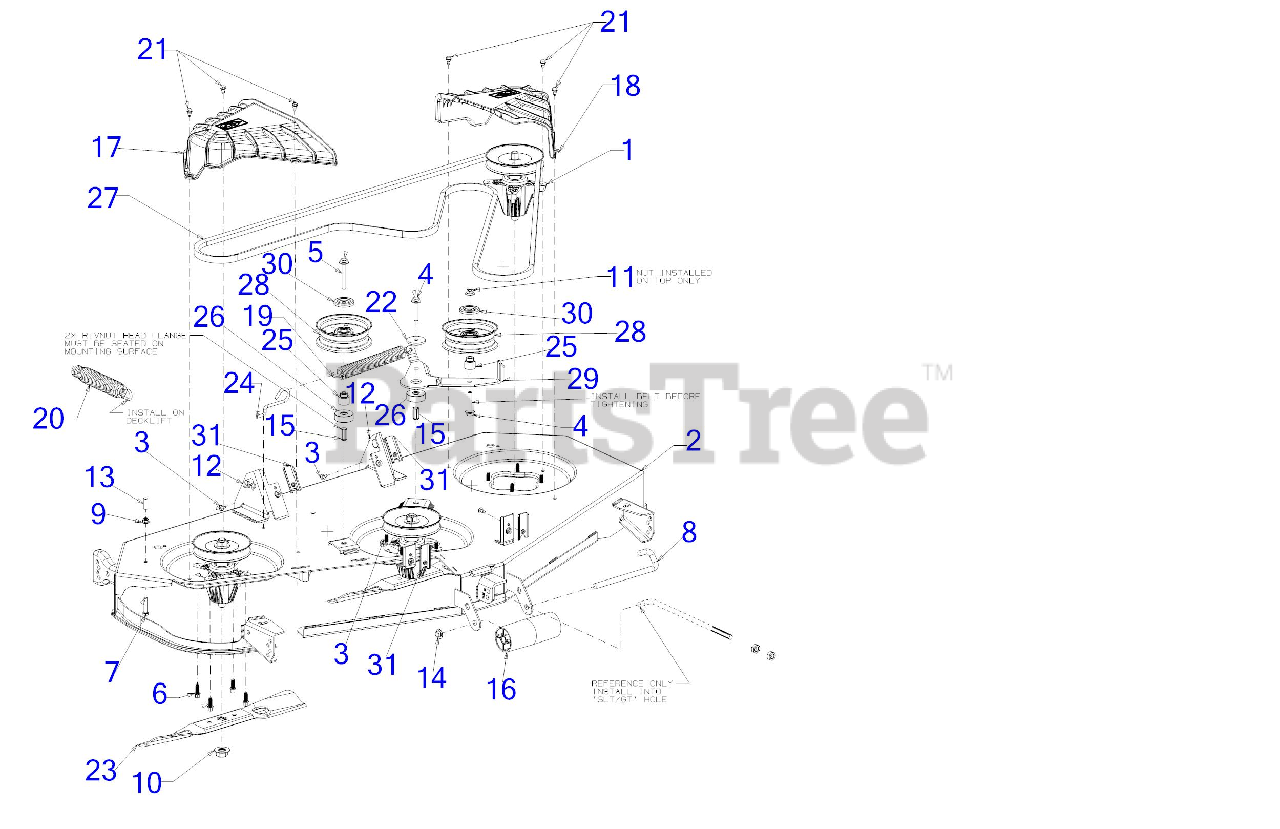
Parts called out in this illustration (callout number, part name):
1	SPINDLE ASSEMBLY
1	Cub Cadet 54" SPINDLE (06978 W/HDW)
2	54" DECK SHELL
3	SCREW M6-1 x .625
4	SCREW 3/8-16 x 2.0
5	SCREW 3/8-16 x 2.75 GR5
6	SCREW 5/16-18 X .875
7	SCREW 5/16-18 x 1.5 LG
8	ROLLER PIN 1/2 x 7.31
9	FLANGE LOCK NUT 5/16-18
11	FLANGE LOCK NUT
12	BOW TIE COTTER PIN
15	NUT RIVET 3/8-16
17	SPINDLE COVER (RH)
18	SPINDLE COVER (LH)
19	EXTENSION SPRING
20	LIFT ASSIST SPRING
21	SHOULDER SCREW 1/4-20 x .50
22	SHOULDER SPACER
23	18.61" BLADE (2N1)
23	Cub Cadet 54" HI LIFT BLADE SET
23	Genuine Factory Parts 54" BLADE SET
23	54" 6 PT STAR LOW LIFT/SAND BLADE
23	Cub Cadet 54" LOWLIFT BLADE SET
23	Genuine Factory Parts 54" LOWLIFT BLADE SET
23	54" 6 PT STAR XTREME MULCH BLADE
23	Cub Cadet 54" XTREME BLADE SET
23	Genuine Factory Parts 54" XTREME MULCH BLADE SET
24	DECK SPRING HOOK
25	SHOULDER SPACER
26	SPACER .385ID x 1.75OD x .585THK
27	V-BELT B SEC x 139 LG
27	Cub Cadet 54" DECK DRIVE BELT
27	Genuine Factory Parts 54" DECK BELT
28	IDLER PULLEY 4.50" DIA
29	IDLER PIVOT BRACKET
30	IDLER PULLEY CAP
